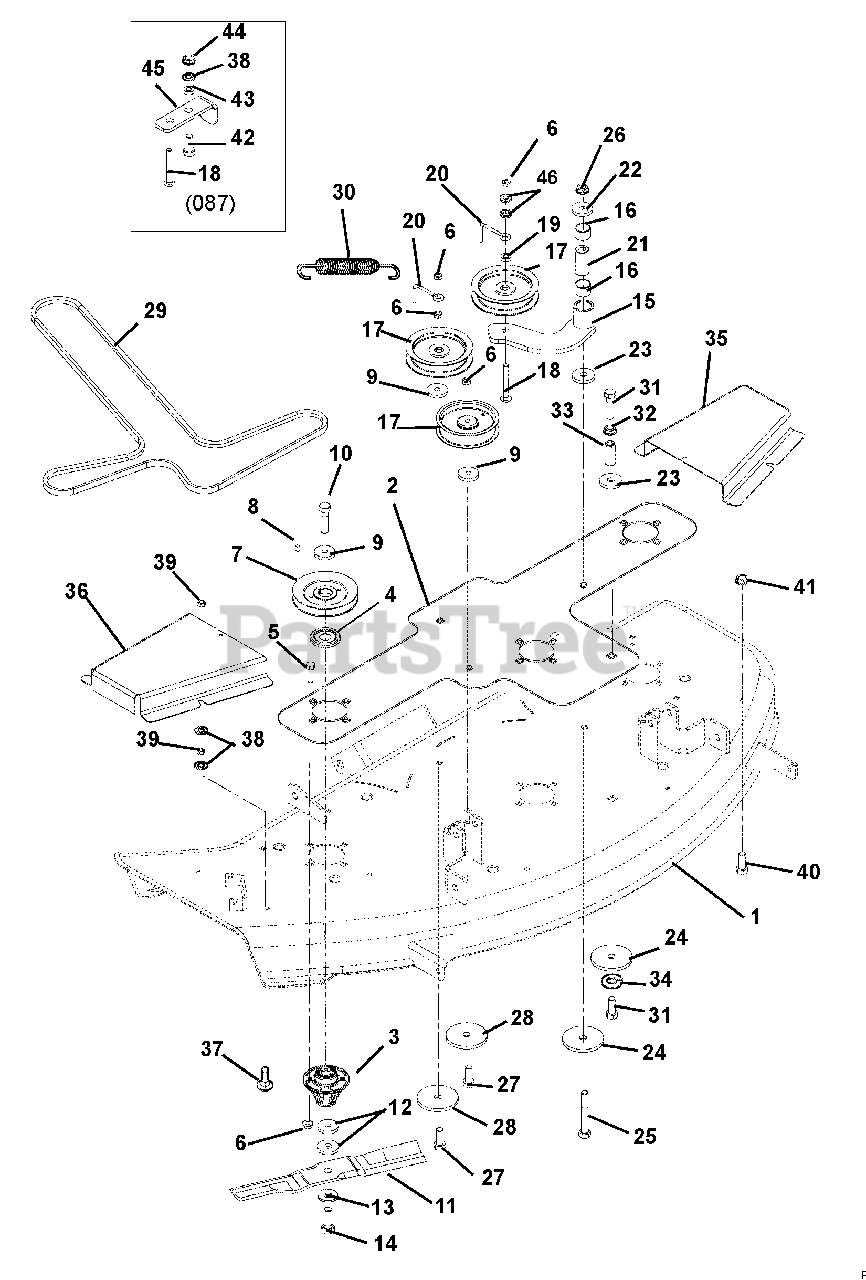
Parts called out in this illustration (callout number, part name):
1	WELDMENT, ZOOM 50" DECK
1	WELDMENT, 40" STAMPED DECK
2	50 DOUBLER PLATE, ZOOM
2	DOUBLER PLATE, ZOOM 40
3	SPINDLE ASSEMBLY
4	DUST CAP
5	@BLT-RDHDSQNK .38-16X1.25 G5YZ
6	@NUT-LK-NYL-FLG .38-16 YWZC
7	SHEAVE, 4.75 DIA A-SECTION
7	SHEAVE, 4.25 DIA A-SECTION
8	KEY, SQ .25 X .38 X .25
9	WSHR,FLT STL.406X1.50X.245YWZC
10	BLT-HEX .38-16X1.0 GR8 YZ EP30
11	BLADE
11	MOWER BLADE, 13.94"
12	WSHR-FLT .640X1.75X.250 YWZC
13	WSHR-BLVL .669X1.535X.138
14	BLT-HEX .62-18X1.75 GR8 YWZC
15	WMT, IDLER ARM
16	BRG, 1.00 X 1.12 X .75
17	IDLER, FLAT .38X4.00X1.06
18	@BLT-RDHDSQNK .38-16X3.50 G5YZ
18	@BLT-RDHDSQNK .38-16X2.50 G5YZ
19	BSHG-SLV .391X.688X.52 PM
20	BELT FINGER
21	BSHG, SPCR .502X.997X2.03 PM
22	WSHR-FL-STL.511X1.441X.125 YWZ
23	WSHR-FL-STL .515X1.625X.250 YZ
24	WASHER, FLAT .531X3.000X.25
25	@BLT-HEX .50-13X3.50 GR5 YWZC
26	@NUT-LK-TOP-FLG .50-13 YWZC
27	@BLT-HEX .38-16X2.75 GR5 YWZC
28	WSHR-FL-STL .469X2.00X.25 YWZC
29	V-BELT, A-WRAPPED
29	V-BELT, HA-WRAPPED
30	EXTENSION SPRING
31	@BLT-HEX .50-13X1.25 GR5 YWZC
32	NUT-SPNLK-FLG .50-13 YWZC
33	NUT, COUPLING 1/2-13X1.75 YWZC
34	@WSHR-LK .50X.125 REG YWZC
35	BELT COVER, LEFT
35	BELT COVER, LEFT ZOOM 40
36	BELT COVER, RIGHT
36	BELT COVER, RIGHT ZOOM 40
37	@BLT-RHDSHSQNK.31-18X1.25 G5YZ
38	@WSHR-FL-STL.38X.875X.083 YWZC
39	@NUT-LK-NYL-FLG .31-18 YWZC
40	@BLT-HEX .31-18X.75 GR5 YWZC
41	@NUT-SPNLK-FLG .312-18 YWZC
42	@BLT-HEX .38-16X1.00 GR5 YWZC
43	BSHG-SLV .377X.624X.235
44	@NUT-LK-TOP-FLG .38-16 YWZC
45	BELT FINGER
46	BSHG-FLG .406X.88X.270X.140
